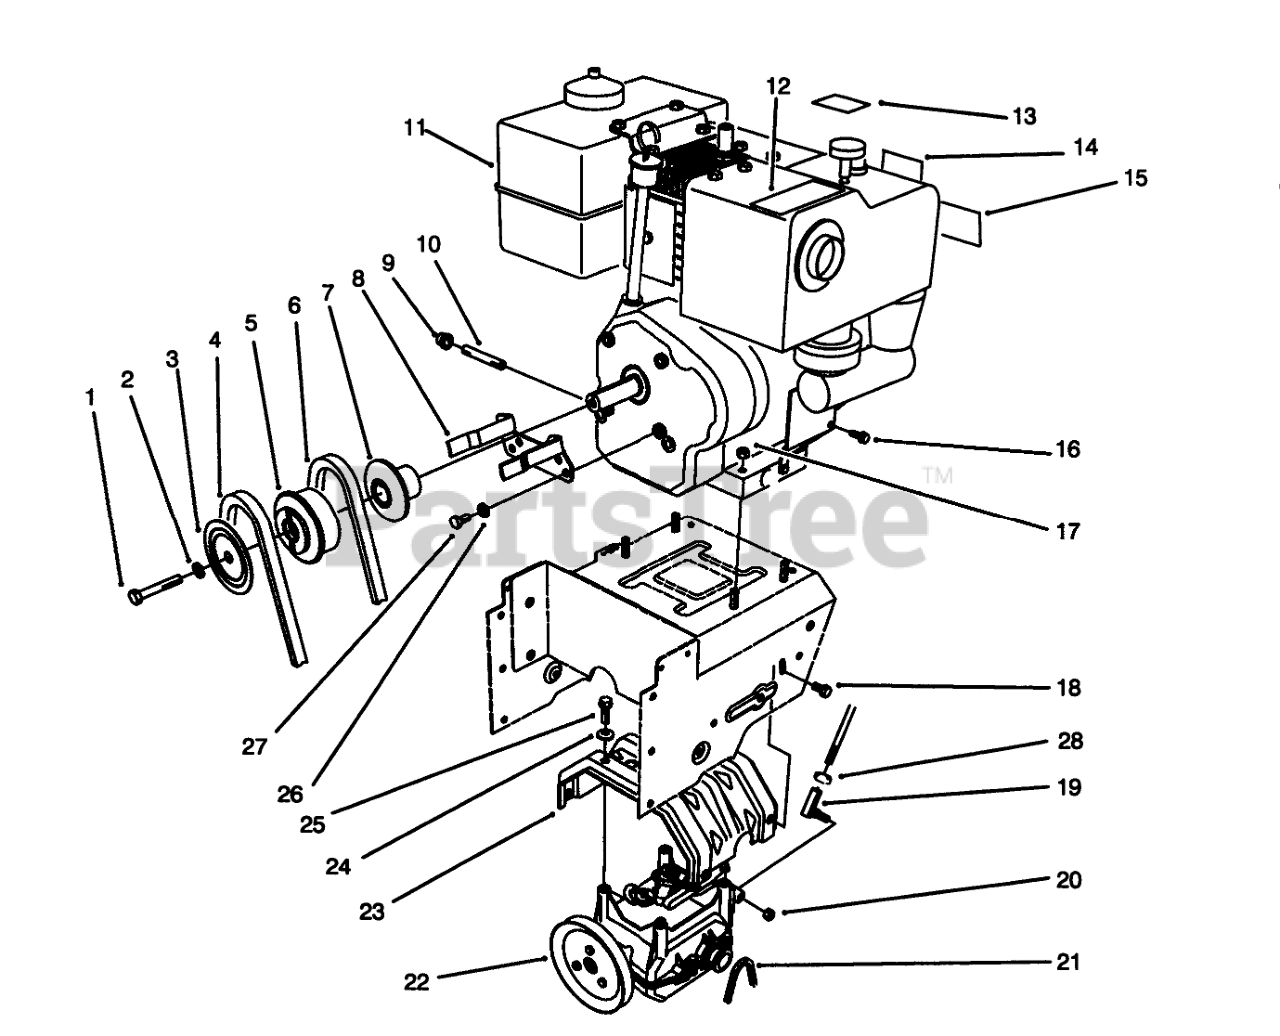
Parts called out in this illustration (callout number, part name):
1	SCREW-HH
2	WASHER-LOCK
3	SHEAVE-HALF, IMPELLER
4	V-BELT, IMPELLER
5	PULLEY-ENGINE, CENTER
6	V-BELT, TRACTION
7	SHEAVE-HALF, TRACTION
8	Guide-Belt
9	CAP-PIPE
10	NIPPLE-PIPE
12	DECAL-WARNING, HOT SURFACE
13	DECAL - THROTTLE, INT'L
14	DECAL - PRIMER, INT'L
15	DECAL - CHOKE
16	SCREW-HH
17	NUT-HF
18	SCREW-HHF
19	JOINT-BALL
20	NUT-LOCK, NI
21	CHAIN
22	TRACTION GEARCASE ASM
23	Frame-Transmission
24	WASHER-SPRING
25	SCREW-HWHTF
26	WASHER-LOCK
27	SCREW-HH
28	NUT-HJ
